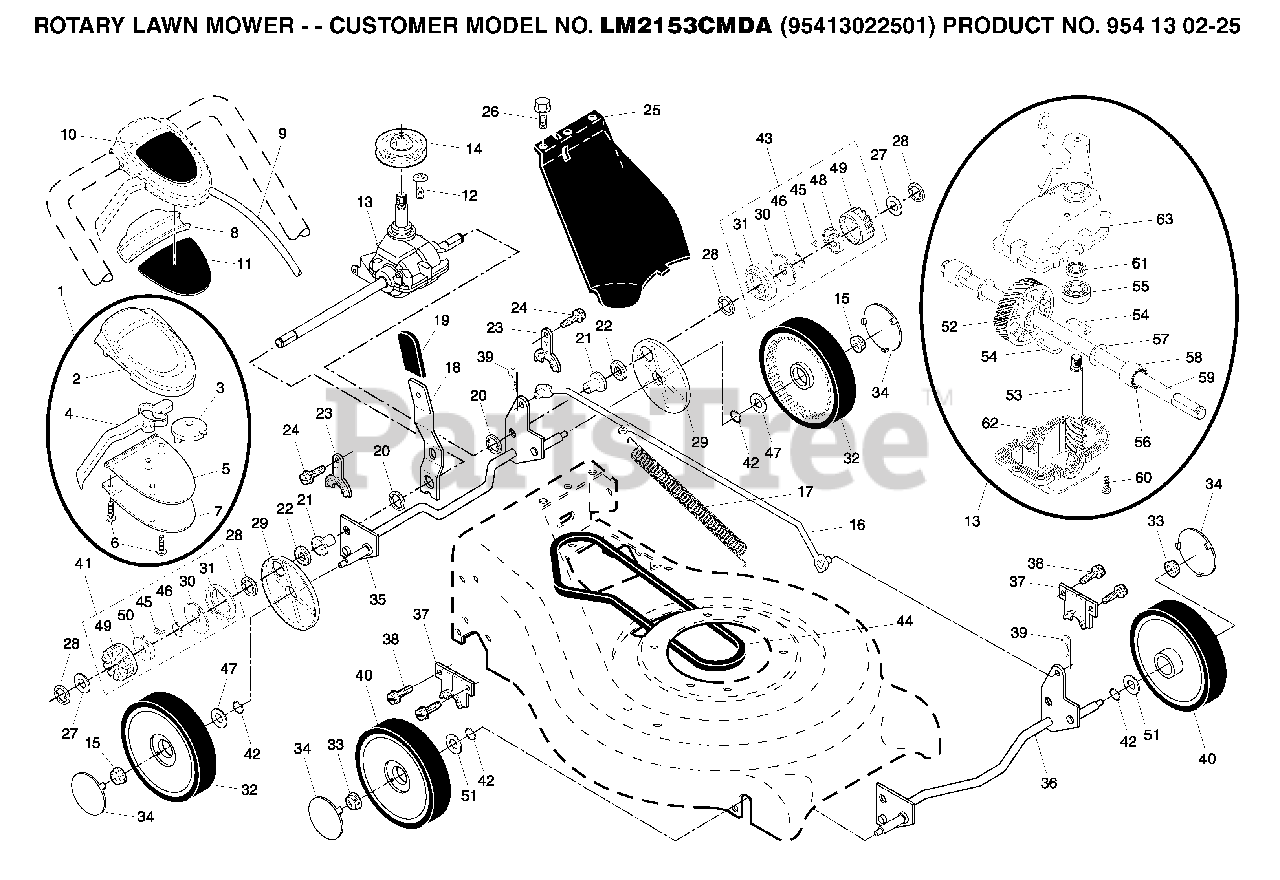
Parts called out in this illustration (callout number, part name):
3	PULLEY, DRIVE CONTROL
6	SCREW, PHILLIPS HEAD 10 X 5/8
7	BRACKET, DRIVE CONTROL
8	EA WLK COVER PLATE.BLK
9	DRIVE CONTROL CABLE
13	TRANSMISSION.21.RWGD
15	HEX FLANGE LOCKNT
16	ROD CONNECTING
17	SPRING
18	SPRING.SELECTOR.SPT.21
19	KNOB, SELECTOR SPRING
21	RP BEARING SUPPORT
22	BEARING, BALL
23	BRACKET
27	WASHER
28	E-RING 7/16 RE
29	COVER.DUST.WHEEL
30	DISC.DRIVE.21.EZ-WALK
31	SEAL.PINION
32	WHEEL, 9 X 2
33	HEX FLANGE LOCKNT
34	HUBCAP
35	SHAFT.ASM.REAR.TORQUE
36	SHAFT ASSY FRONT
37	RETAINER.FRONT.SHAFT
39	RETAINER CLIP
40	WHEEL ASMBLY FRONT
41	PINION ASSY, RH
42	O-RING
43	PINION ASSY, LH
44	V-BELT
45	PAWL.DRIVE.21.EZ-WALK
46	SPRING, TORSION
47	WASHER FLUT
48	RETAINER.DRIVE.21.EZ-WALK.LT
49	GEAR, PINION
50	RETAINER, DRIVE, RH
51	WASHER PM
61	CASE, LOWER
62	CASE, UPPER
63	GEAR.24.TOOTH.WALK.MOWER
64	SHAFT INPUT
65	WIRE, FORMED
67	SEAL.OUTPUT.SHAFT
70	SHAFT.OUTPUT.RGD.VS/EZ
72	SEAL INPUT SHAFT
